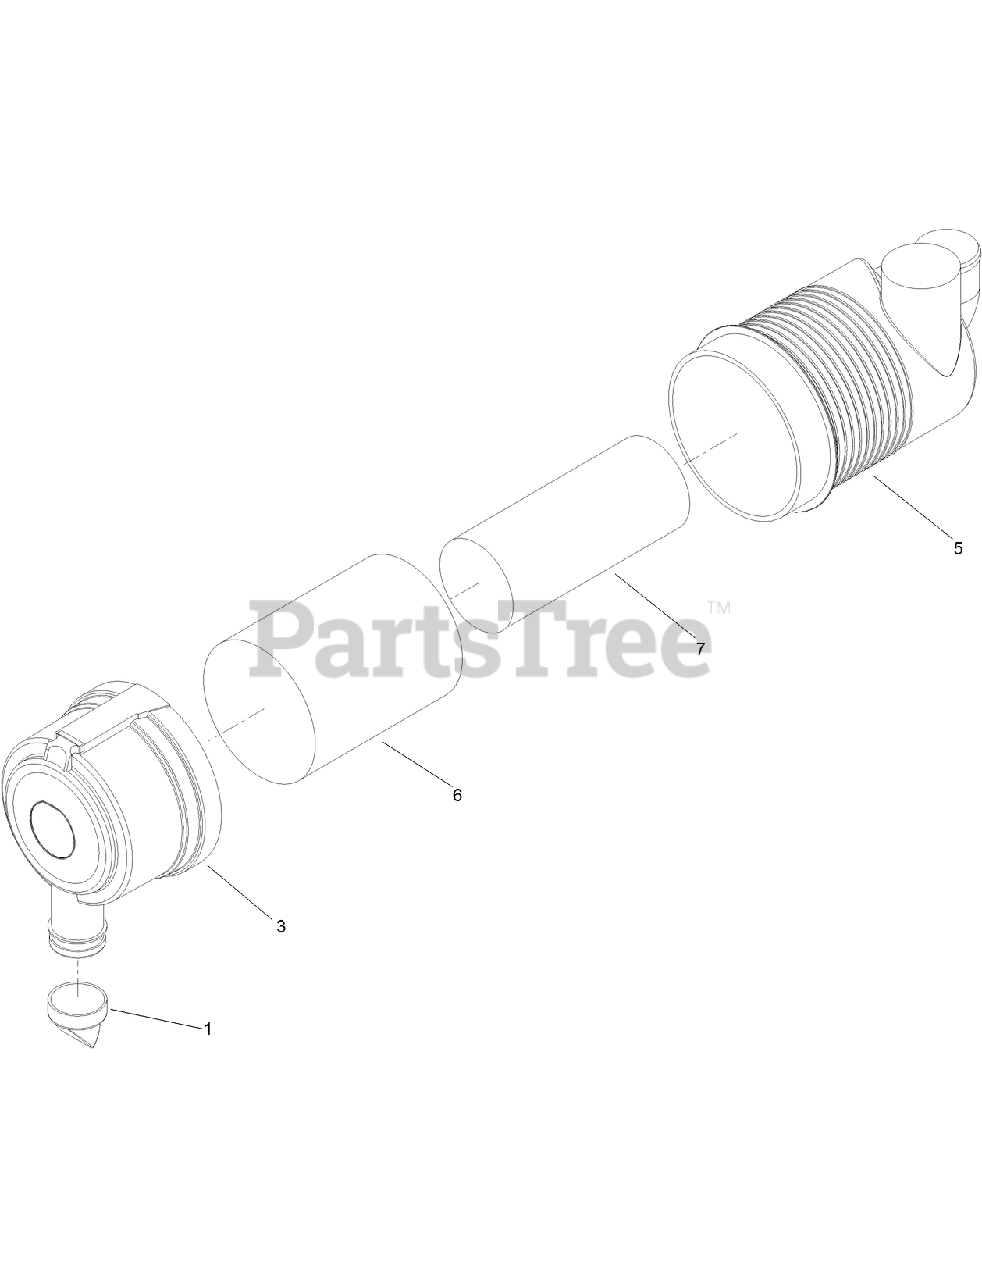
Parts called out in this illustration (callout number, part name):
1	VALVE-VACUATOR
5	Body ASM
6	FILTER-AIR
7	FILTER-AIR
